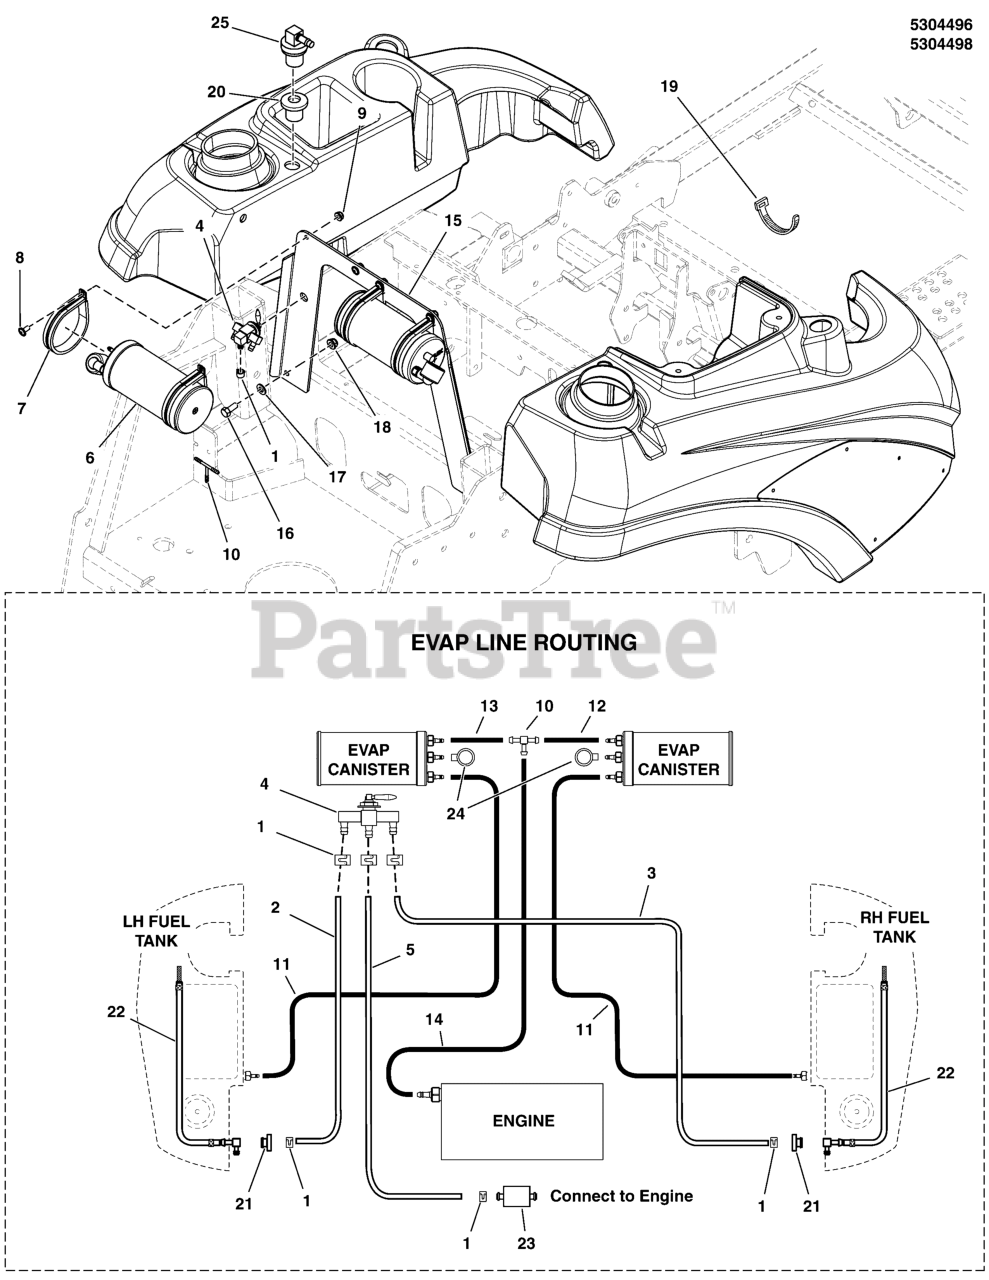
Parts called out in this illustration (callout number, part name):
1	CLAMP, HOSE, EXTERNAL, 1/2 - RED
2	HOSE, 1/4" FUEL, 13.00"
3	HOSE, 1/4" FUEL, 26.50"
4	VALVE, FUEL SHUT-OFF, 12773
5	HOSE, 1/4" FUEL, 23.00"
6	CNSTR, CARB, 6 GAL
7	CLAMP, 3" ID, CUSHIONED, STAINLESS
9	NUT, 1/4-20 HEX NYLOCK FLANGE
10	FITTING, 3/16" TEE, BARB TYPE, HDPE
11	HOSE, VAPOR, 5MM ID, 22.00 LG
12	HOSE, VAPOR, 5MM ID, 5.00 LG
13	HOSE, VAPOR, 5MM ID, 19.00 LG
14	HOSE, VAPOR, 5MM ID, 24.50 LG
15	PLATE, MOUNT, CANISTER, IS2100Z - BLK
16	BOLT, 5/16-18 X 3/4 GD5
17	WASHER, 5/16" SAE
18	NUT, 5/16-18 HEX NYLOCK FLANGE
19	TIE, SELF-LOCKING, 12"
20	GROMMET (SV)
21	BUSHING-FUEL TANK RED RUBBER
22	HOSE ASSEMBLY (SV)
23	FUEL FILTER (SV)
24	DUST FILTER, CANISTER (SV)
25	REMOTE VENT ASSEMBLY
